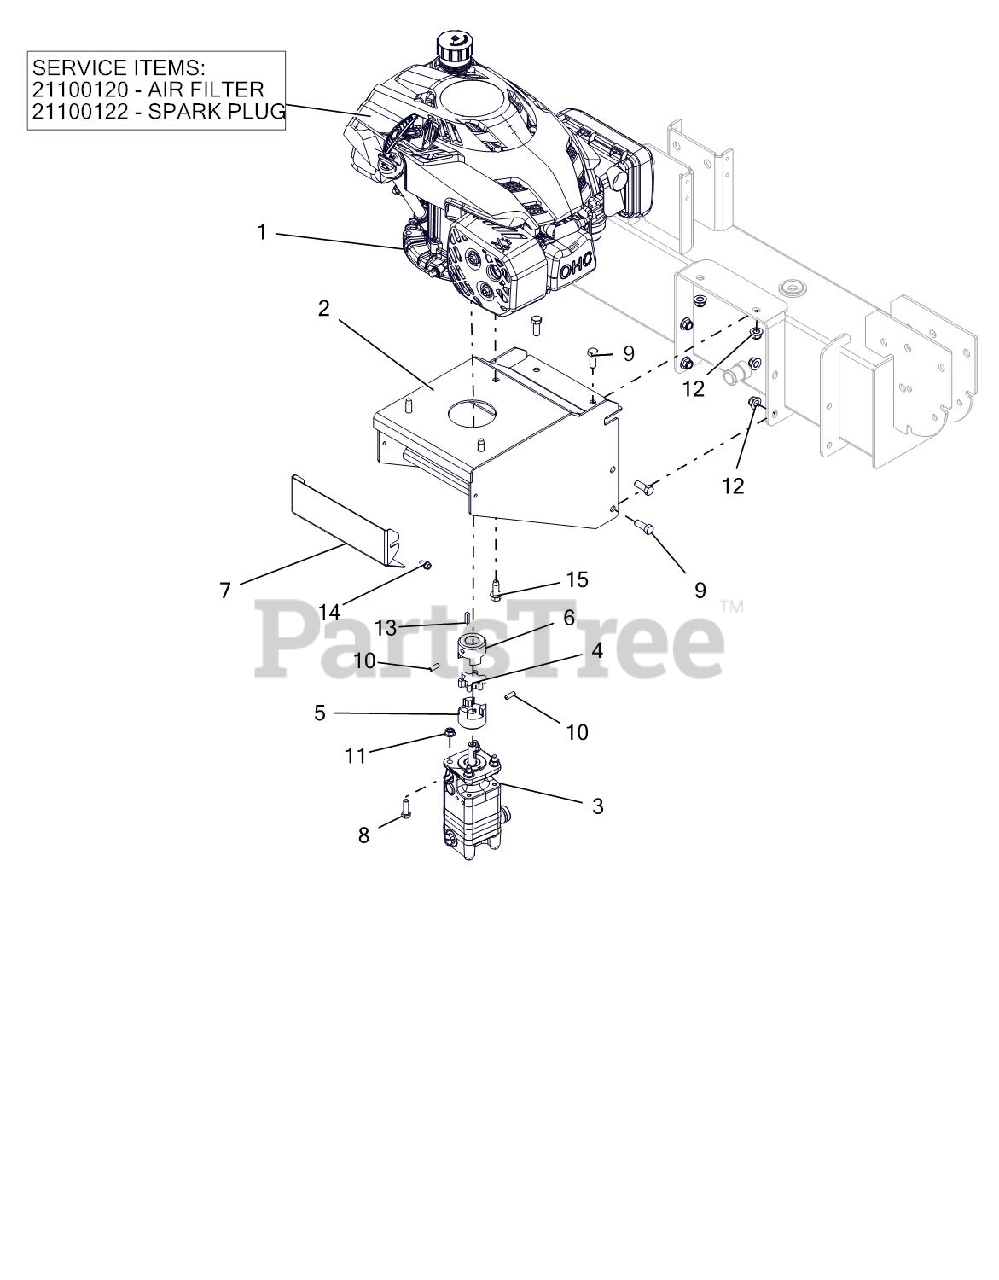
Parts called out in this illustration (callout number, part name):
1	FILTER, AIR- SUBARU PAPER
1	PLUG, SPARK
1	ENGINE, SUBARU EA190 (CARB) LS
2	ENGINE MOUNT W/SAFTY DECAL-27T
3	PUMP,SPLITTER-11 GPM
4	SPIDER - URETHANE
5	COUPLER - DRIVE 1/2"
6	COUPLER - DRIVE, 7/8"
7	COVER-COUPLER
8	@BLT-HEX .31-18X1.00 GR5 YWZC
9	@BLT-HEX .38-16X1.00 GR5 YWZC
10	SCR,SET .25-20X.75 PCPT SH
11	@NUT-LK-TOP-FLG .31-18 YWZC
12	@NUT-LK-NYL-FLG .38-16 YWZC
13	KEY-SQ .188X.75X.188
14	SCR-TAP .25-20X.50 HWH TR YWZ
15	@SCR-TAP .38-16X1.00 HWH TR YZ
